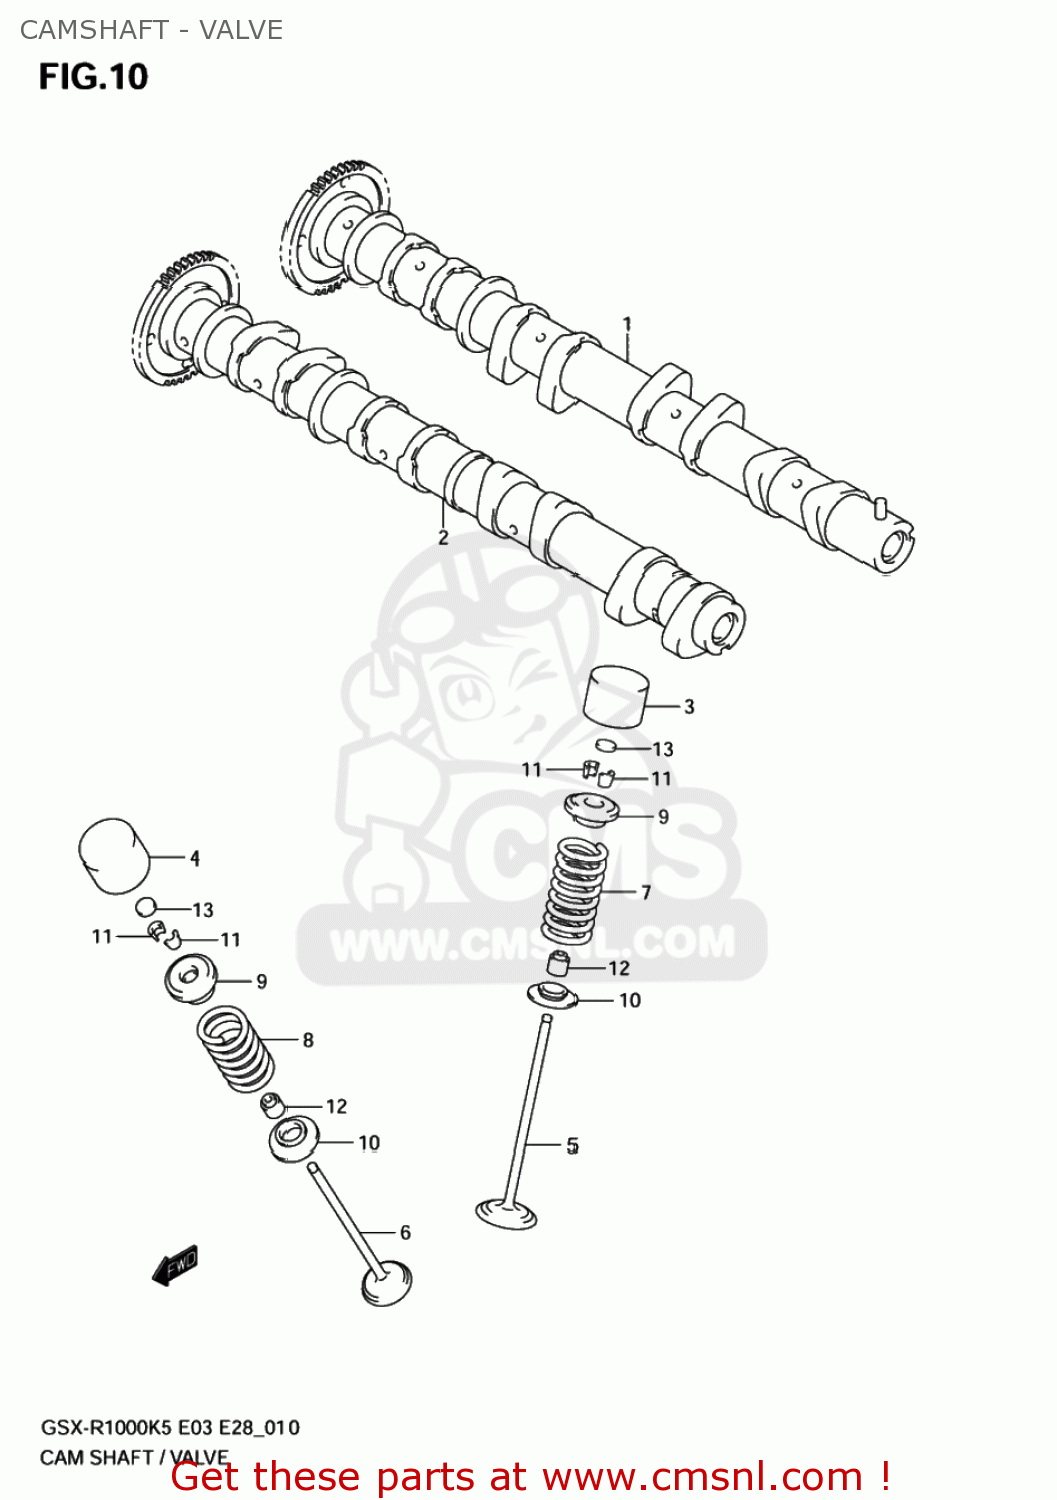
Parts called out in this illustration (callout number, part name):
1	CAMSHAFT,INTAKE
2	CAMSHAFT,EXHAUST
3	TAPPET
4	TAPPET,EXHAUST
5	VALVE,INTAKE
6	VALVE,EXHAUST
7	SPRING,VALVE
8	SPRING,VALVE
9	RETAINER,VALVE SPRING
10	SEAT,VALVE SPRING
11	COTTER VALVE
12	SEAL,OIL(4.5X10X8)
13	SHIM,TAPPET
14	SHIM SET,TAPPET
15	CASE,TAPPET SHIM
